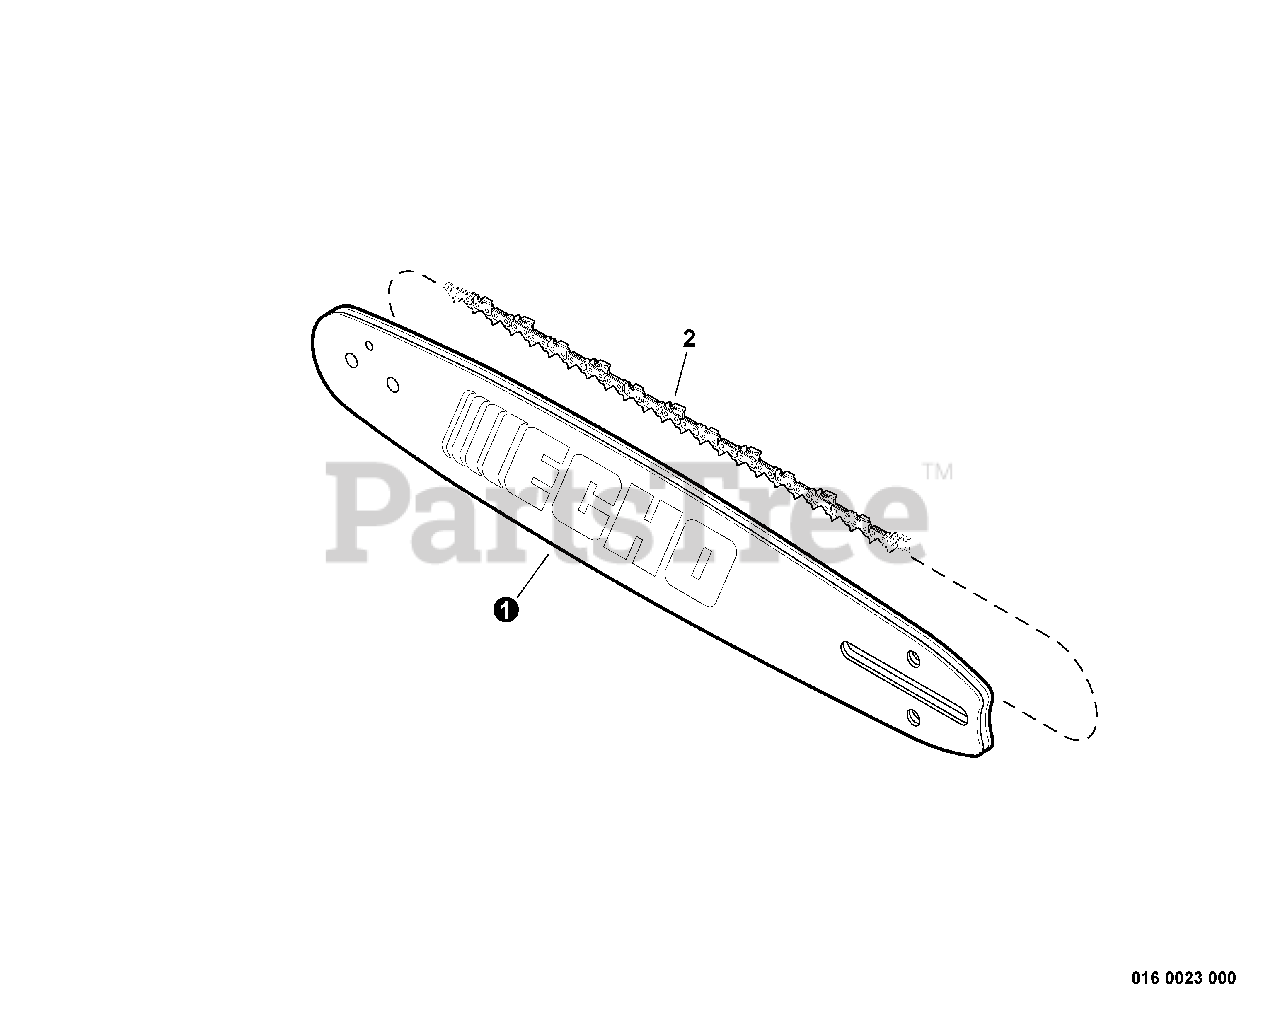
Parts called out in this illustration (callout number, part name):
1	GUIDE BAR - 16" (40cm)
1	GUIDE BAR - 18" (45cm)
1	GUIDE BAR - 20" (50cm)
2	SAW CHAIN - 16" (40cm)
2	SAW CHAIN - 18" (45cm)
2	SAW CHAIN - 20" (50cm)
